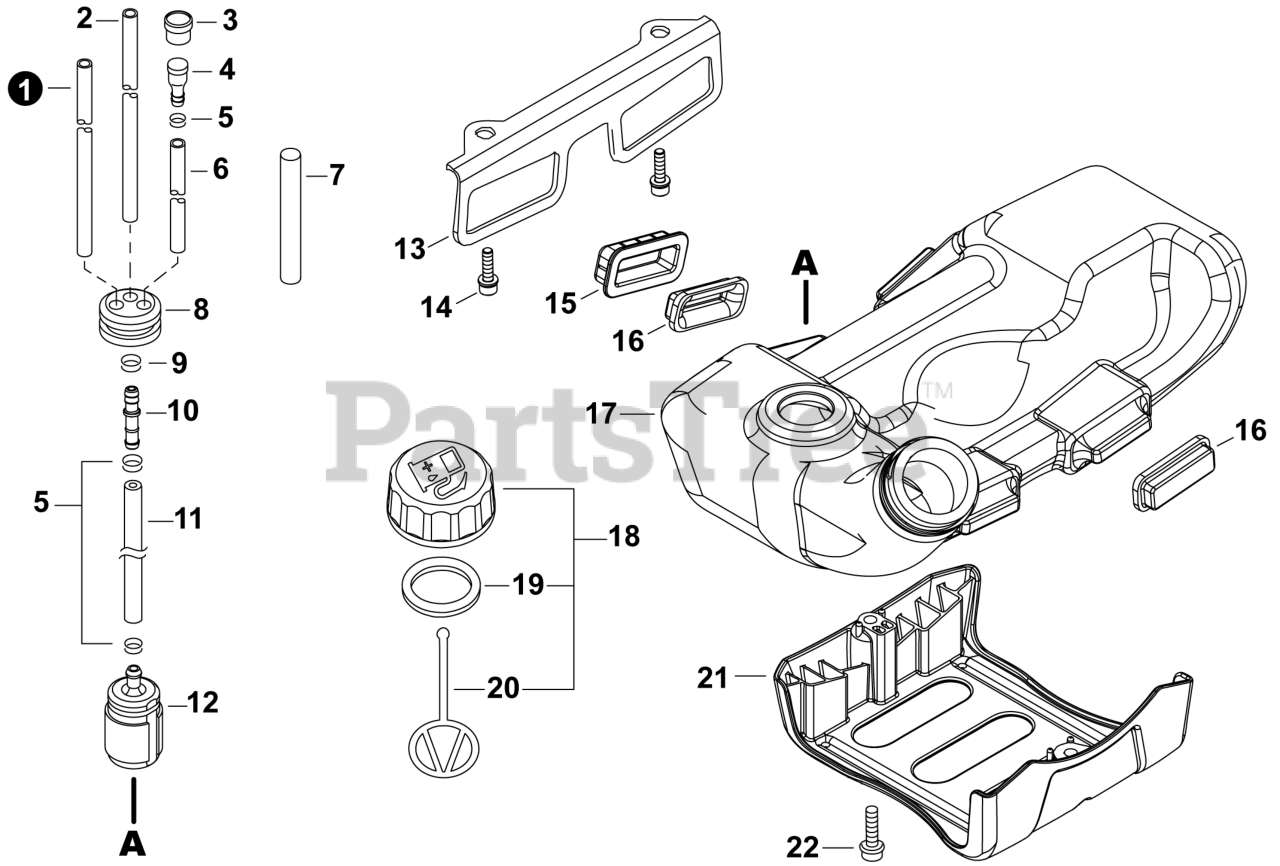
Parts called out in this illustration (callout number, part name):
1	PIPE, FUEL
2	PIPE, FUEL 3×5×180
3	HOLDER, VENT
4	VENT ASSY
5	CLIP Ø6
6	PIPE, FUEL 3×6×140 BLACK
7	TUBE, INSULATOR 8×9×111
8	GROMMET, FUEL
9	CLIP 5.5
10	CONNECTOR, PIPE
11	PIPE, FUEL 3×6×130 BLACK
12	FILTER, FUEL
13	BRACKET, FUEL TANK
14	BOLT, TORX 5×16
15	HOLDER, CUSHION
16	CUSHION, FUEL TANK
17	TANK, FUEL
18	CAP ASSY, FUEL
19	GASKET, FUEL CAP
20	CONNECTOR, CAP L= 123
21	GUARD, FUEL TANK
22	BOLT, TORX 5×16
